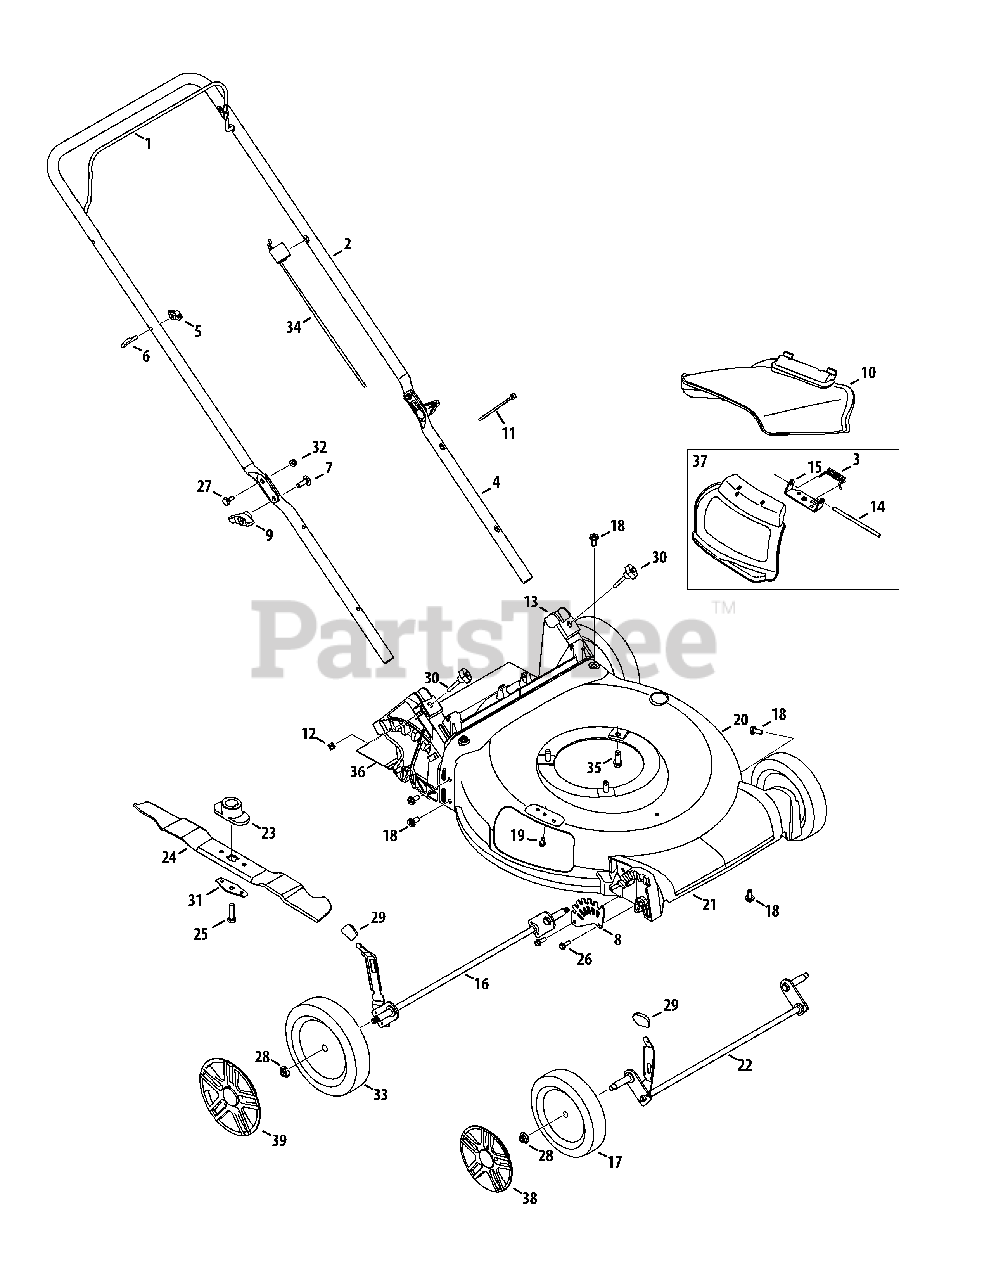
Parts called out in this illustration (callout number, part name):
1	Blade Control
2	Upper Handle, Adjustable
3	Torsion Spring
4	Lower Handle
5	Wing Nut
6	Rope Guide
7	Carriage Screw ,5/16-18
8	Front Height Adjuster Plate
9	Wing Knob
10	Side Chute
11	Cable Tie
12	Nut, Sq., 1/4-20
13	Rear Baffle
14	Hinge Pin
15	Chute Deflector Bracket
16	Rear Axle Assembly
17	Front Wheel, 7 x 2.0, Z, Black
18	Screw, 5/16-14 x .750
19	Screw, 1/4-20 x .500
20	Deck , 21"
21	Front Cover
22	Front Axle Assembly
23	Blade Adapter, 25mm x 1.19
24	Mulching Blade
25	Screw , 3/8-24 x 1.50
26	Screw, 1/4-15 x .750
27	Sldr. Screw, .375 x .126 x 1/4-20
28	Flange Lock Nut, 3/8-16
29	Adjustment Lever Knob
30	Wing Nut
31	Blade Bell Support
32	Nut, Flange Lock, 1/4-20
33	Rear Wheel, 8 x 2.0, Z, Black
34	Control Cable (Briggs)
35	TT Sems Screw, 3/8-16 x 1.0
36	Trail shield
37	Hinged Mulch Plug Assembly
38	Hubcap, 7"
39	Hubcap, 8"
